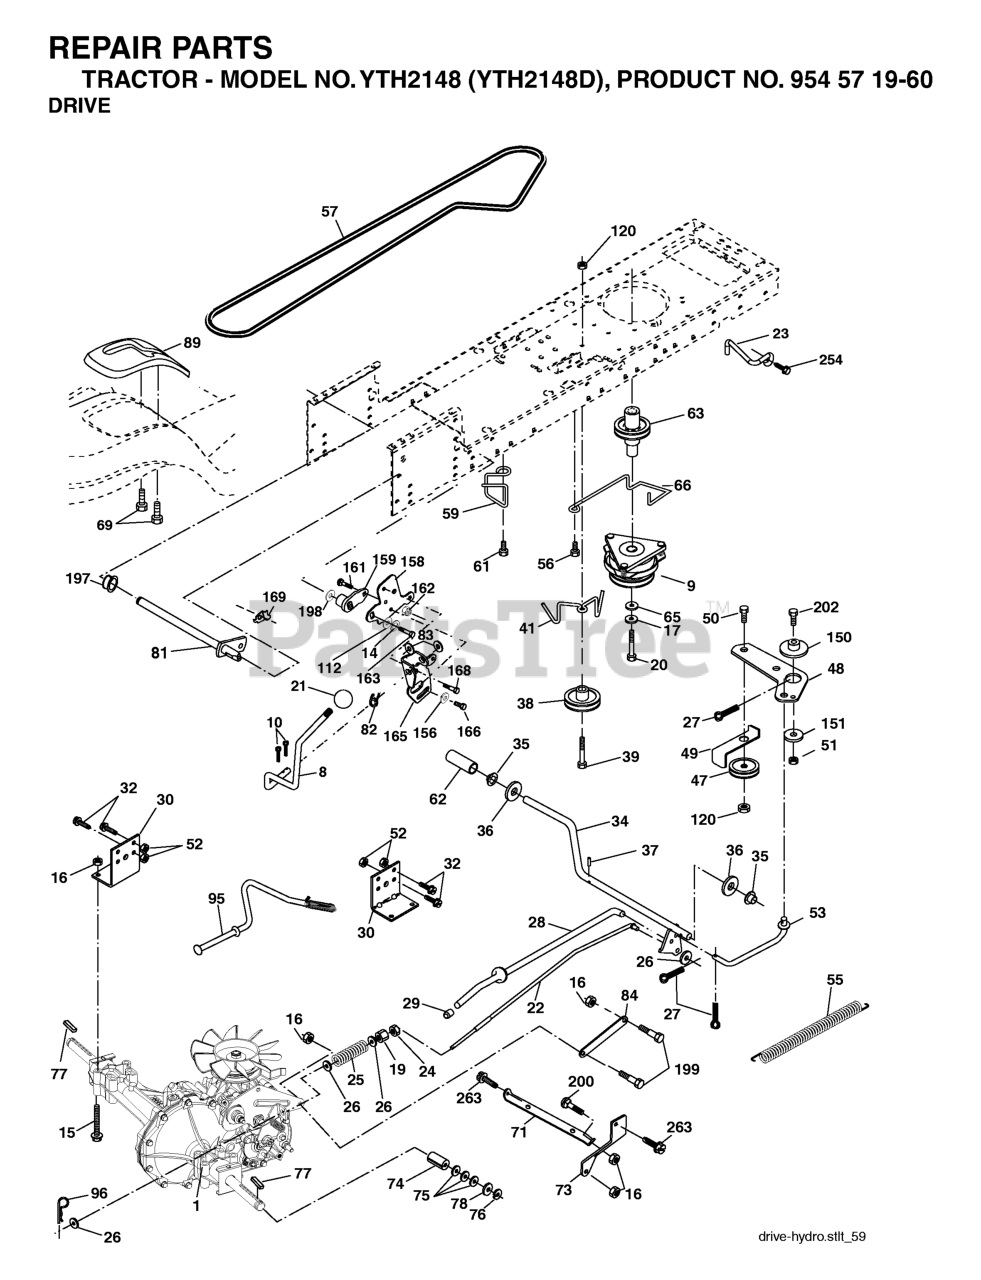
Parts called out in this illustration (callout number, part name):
8	ROD SHIFT FENDER ADJUST STLT
9	CLUTCH, ELECTRIC
10	PIN COTTER
14	LOCKWASHER
15	BOLT HEX 5/16-18 GR 5
16	NUT.71038.31-18.HEX.NYLOCK
19	NUT
20	BOLT HEX 7/16-20X4-1/4"
21	KNOB.DELUXE.(PISTOL.GRIP).BLAC
22	ROD BRAKE HYDRO
23	BRACKET, ANTI-ROTATION
24	NUT
25	SPRING ROD LT
26	WASHER
27	COTTER PIN
28	ROD, PARKING BRAKE
29	PLUNGER CAP
30	BRKT, TRNSXLE MNT 20"
32	BOLT
34	SHAFT, FOOT PEDAL
35	BEARING.NYLON
37	DRIVE PIN
38	PULLEY IDLER COMPOSITE
41	KEEPER, BELT IDLER
47	IDLER PULLEY
48	BELLCRANK, CLUTCH
49	RETAIN BELT
50	BOLT.3/8-16X1.50
52	LOCKNUT
53	LINK, CLUTCH LT
55	SPRING, RETURN LT
56	SCREW.3/8-16
57	DRIVE BELT, LTH & YTH TRACTORS
59	KEEPER, BELT CENTER
61	SCREW 3/8-16X.875
62	PEDAL COVER T
63	PULLEY, ELEC CLUTCH
65	LOCKWASHER
66	KEEPER BELT ENGINE
69	SCREW.HI-LO.CONSOLE
71	STRAP TORQUE LH HYDRO
73	STRAP TORQUE RH HYDRO
74	SPACER AXLE
77	SQUARE KEY
81	SHAFT ASM CROSS TAPERED
82	SHIFT SPRING
83	WASHER
84	LINK TRANSAXLE
89	CONSOLE SHIFT STL AUTO
95	CONTROL ASM. BYPASS HYDRO
96	RETAINER M
120	NUT LOCK FLG 3/8-16 UNC
150	SPACER, RETAINER
151	WASHER 12/32X2X10GA
156	WASHER.SRRTD.5/16
158	BRACKET
159	RB HUB.SHIFT
161	BOLT
162	NUT.CROWNLOCK.1/4
165	RP BRACKET
166	CAPSCREW.HXHD.FLG.5/16-18X.625
168	BOLT.SHOULDER.5/16-18X
169	PLATE.FASTENING.CROSS.SHAFT
197	NYLINER SNAP 5/8" ID
198	WASHER.NYL.7/8IDX.105"HYD CR
199	BOLT SHOULDER 5/16-18 UNC
254	SCREW 3/8-16X1
263	SCREW, 3/8-16X3/4
